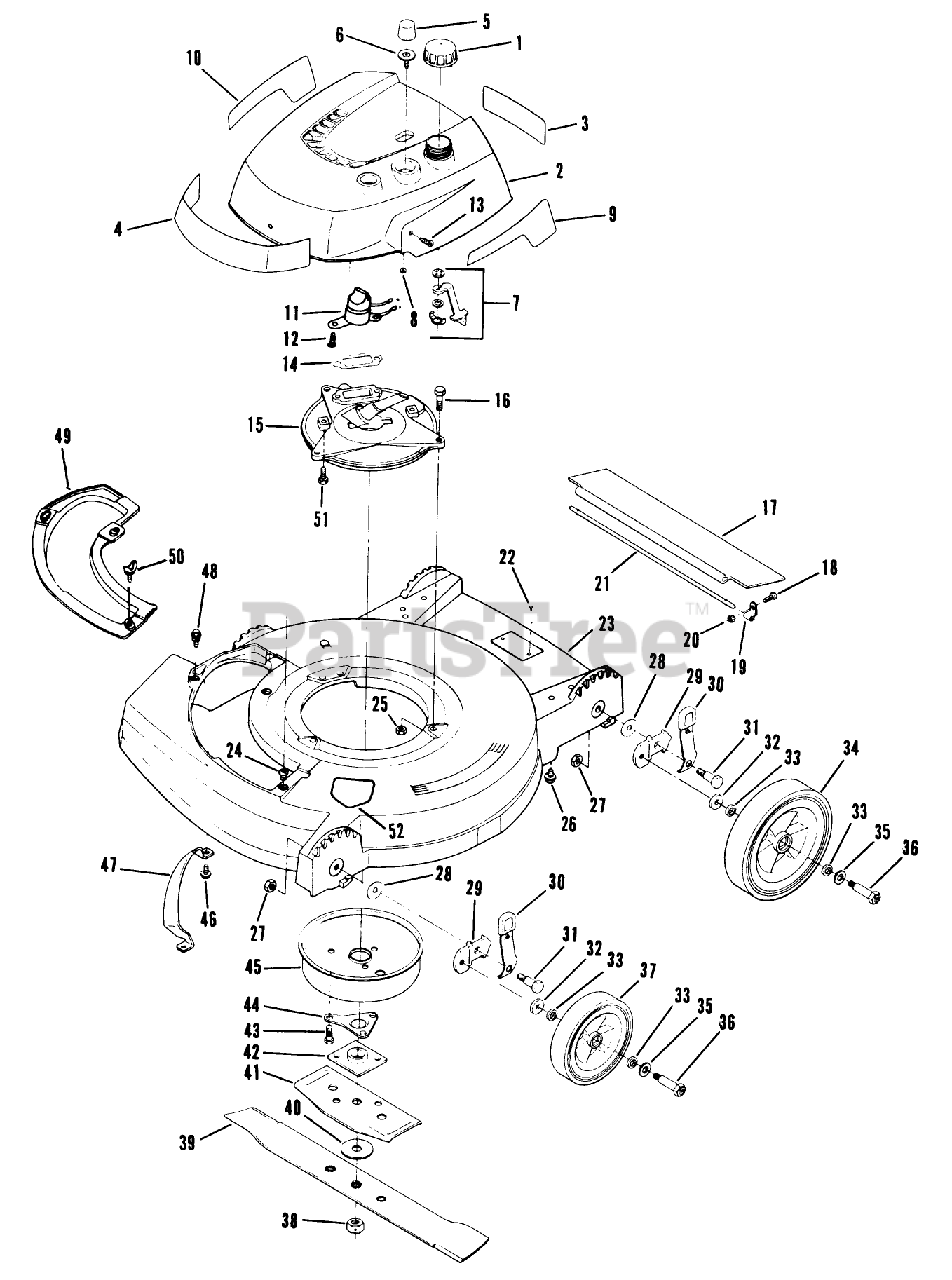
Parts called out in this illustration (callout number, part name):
8	LOCKNUT S
13	SCREW S
16	SCREW
19	CLAMP ROD KMC
20	LOCKNUT E
21	ROD T/SHIELD ADV WIRE
21	ROD 21" ADVANCE
25	NUT-LOCK F
26	SCREW
27	LOCKNUT
28	WASHER
32	WASHER WROUGHT
33	WASHER
35	SPACER
36	BOLT WHEEL
37	WHEEL & TIRE KIT
38	NUT-BLADE
40	WASHER
42	PLATE AND COLLAR ASM
43	SCREW
44	SUPPORT F
47	TOE BAR 19"
47	BAR-TOE
50	WING SCREW LAWRE
51	SCREW V
